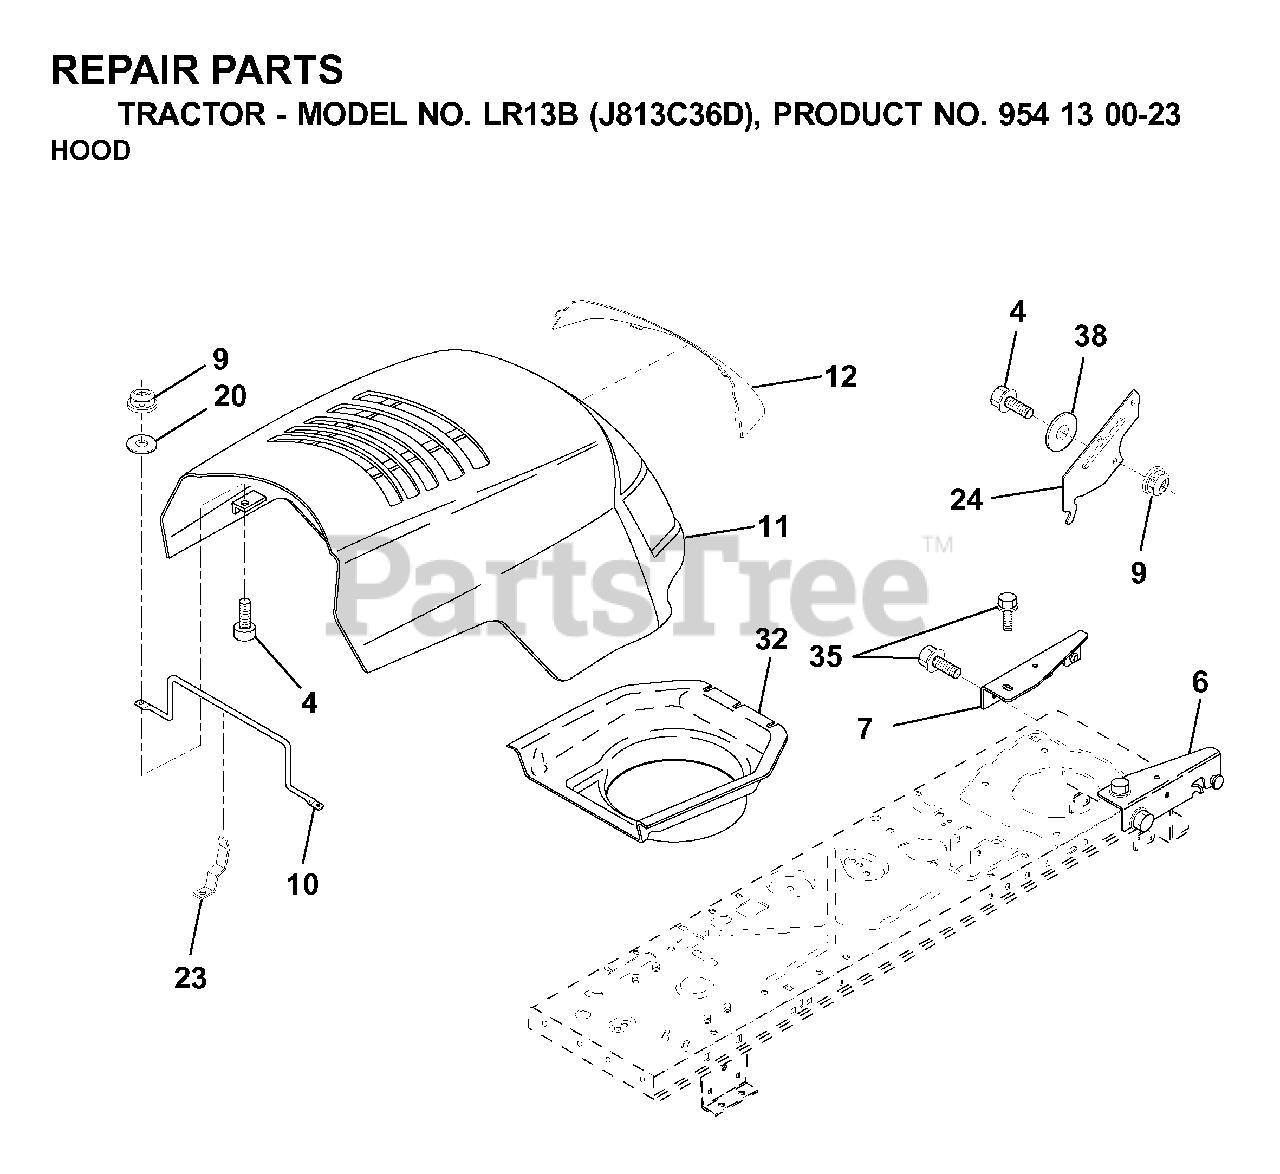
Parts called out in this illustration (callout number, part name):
6	BRACKET ASSY HOOD
7	BRACKET ASSY
9	LOCKNUT
20	WASHER
23	HOOD LATCH
35	SCREW
